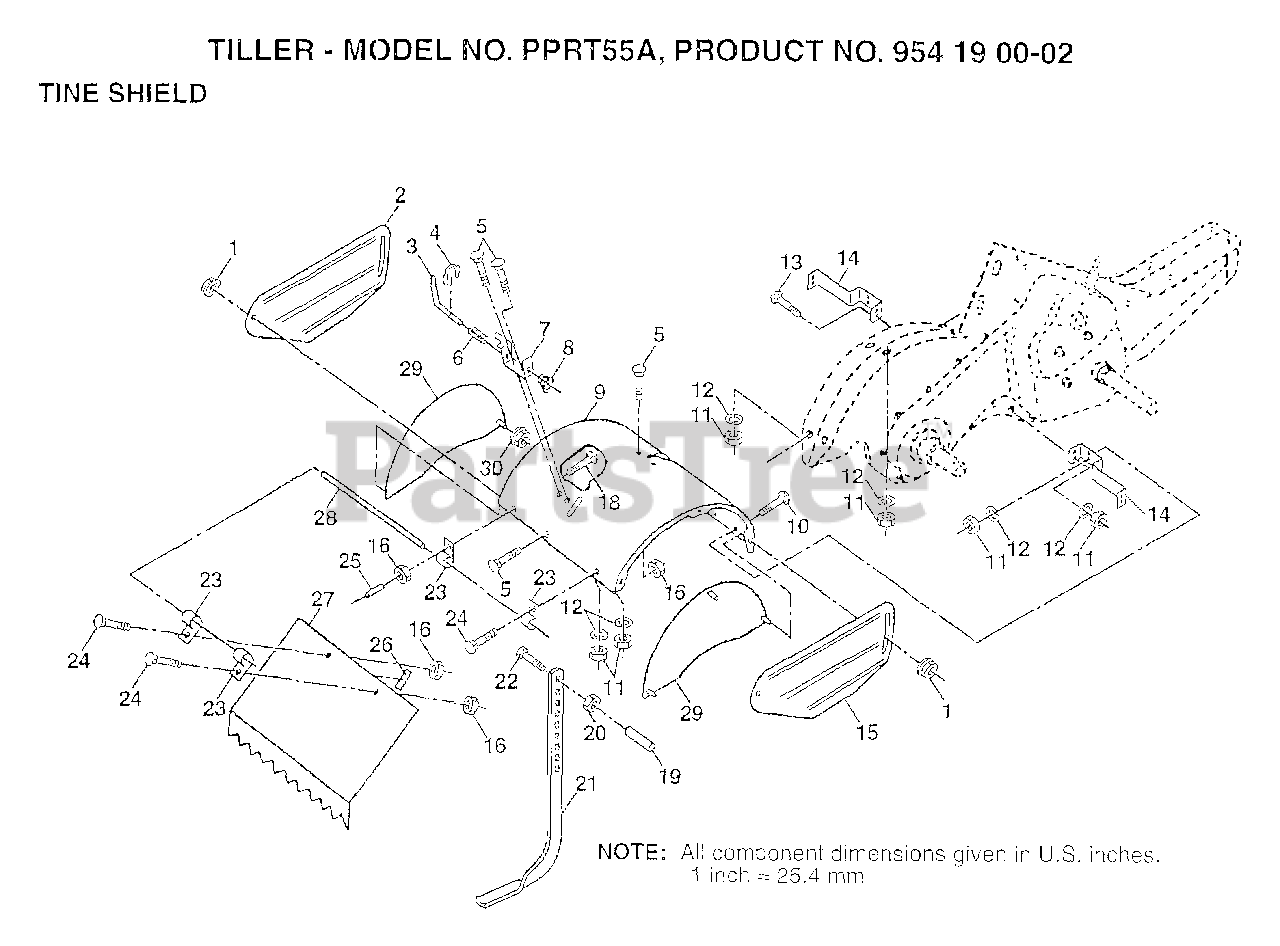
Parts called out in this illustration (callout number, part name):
1	NUT
2	SHIELD SIDE OUTER
3	STAKE PIN TI
4	KLIP RING TI
5	BOLT
6	SPRING TI
7	LATCH BRACKET TI
8	SPRING DEPTH STAKE
9	SHIELD TINE
10	BOLT
11	NUT.HEX.5/16-18
12	LOCKWASHER
13	BOLT
14	"BRACKET,SHIELD"
15	SHIELD SIDE OUTER
16	NUT
18	BOLT
20	NUT.HEX.3/8-16UNC
21	STAKE DEPTH
22	BOLT
23	HINGE CRT
24	BOLT
27	SHIELD LEVELING
29	SHIELD SIDE
30	LOCKNUT TI
